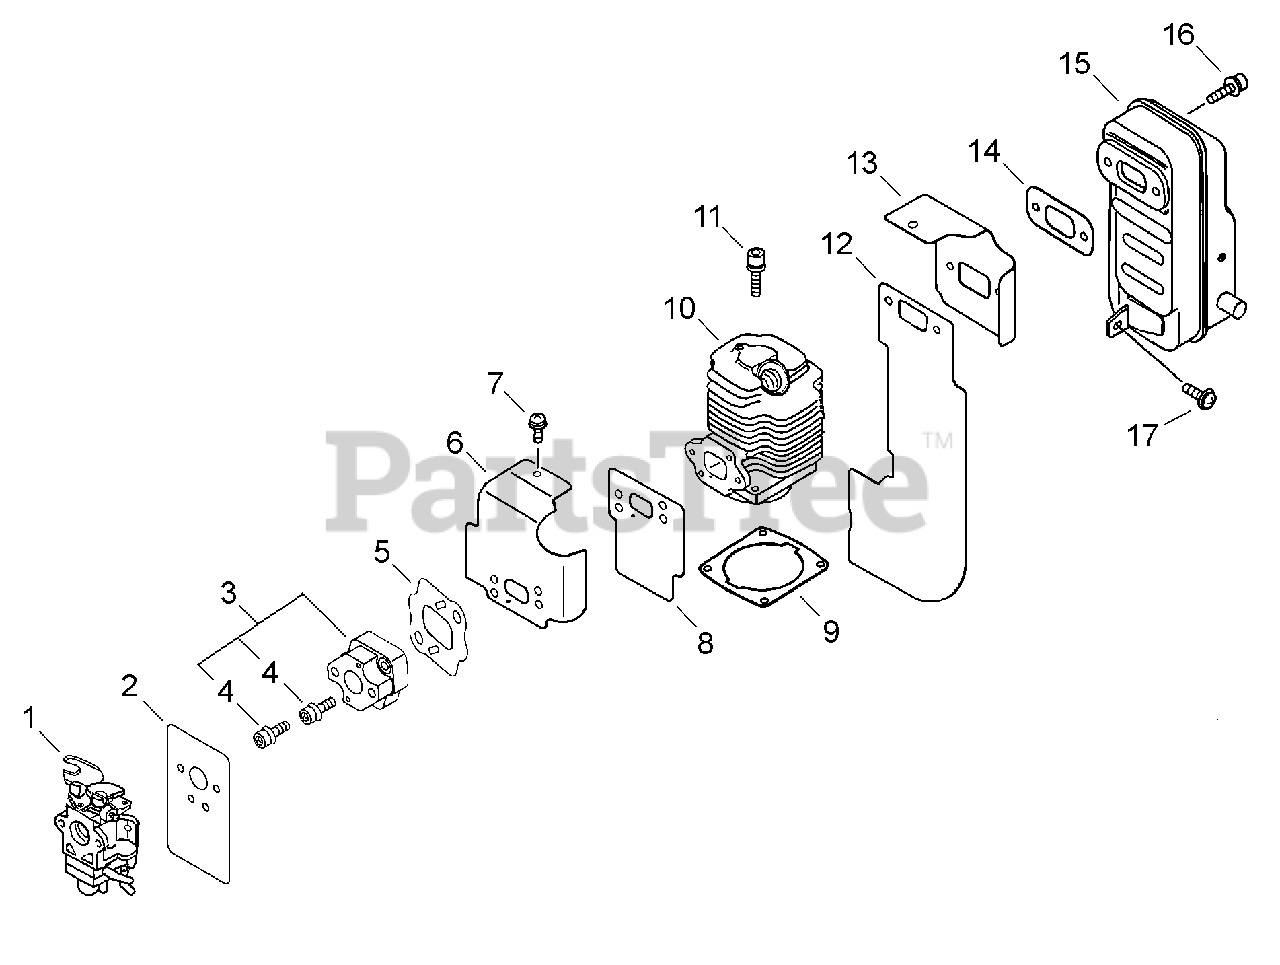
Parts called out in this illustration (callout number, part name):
1	CARBURETOR - WYK-201
2	GASKET, INTAKE
3	INSULATOR KIT, INTAKE
4	BOLT 5×30
5	GASKET, INTAKE
6	COVER, ENGINE - INTAKE
7	SCREW 5×10
8	HEAT SHIELD, INTAKE
9	GASKET, CYLINDER
10	CYLINDER
11	BOLT 5×22
12	HEAT SHIELD, EXHAUST
13	COVER, ENGINE - EXHAUST
14	GASKET, MUFFLER
15	MUFFLER ASSY
16	BOLT 6×20
17	SCREW 5×14
